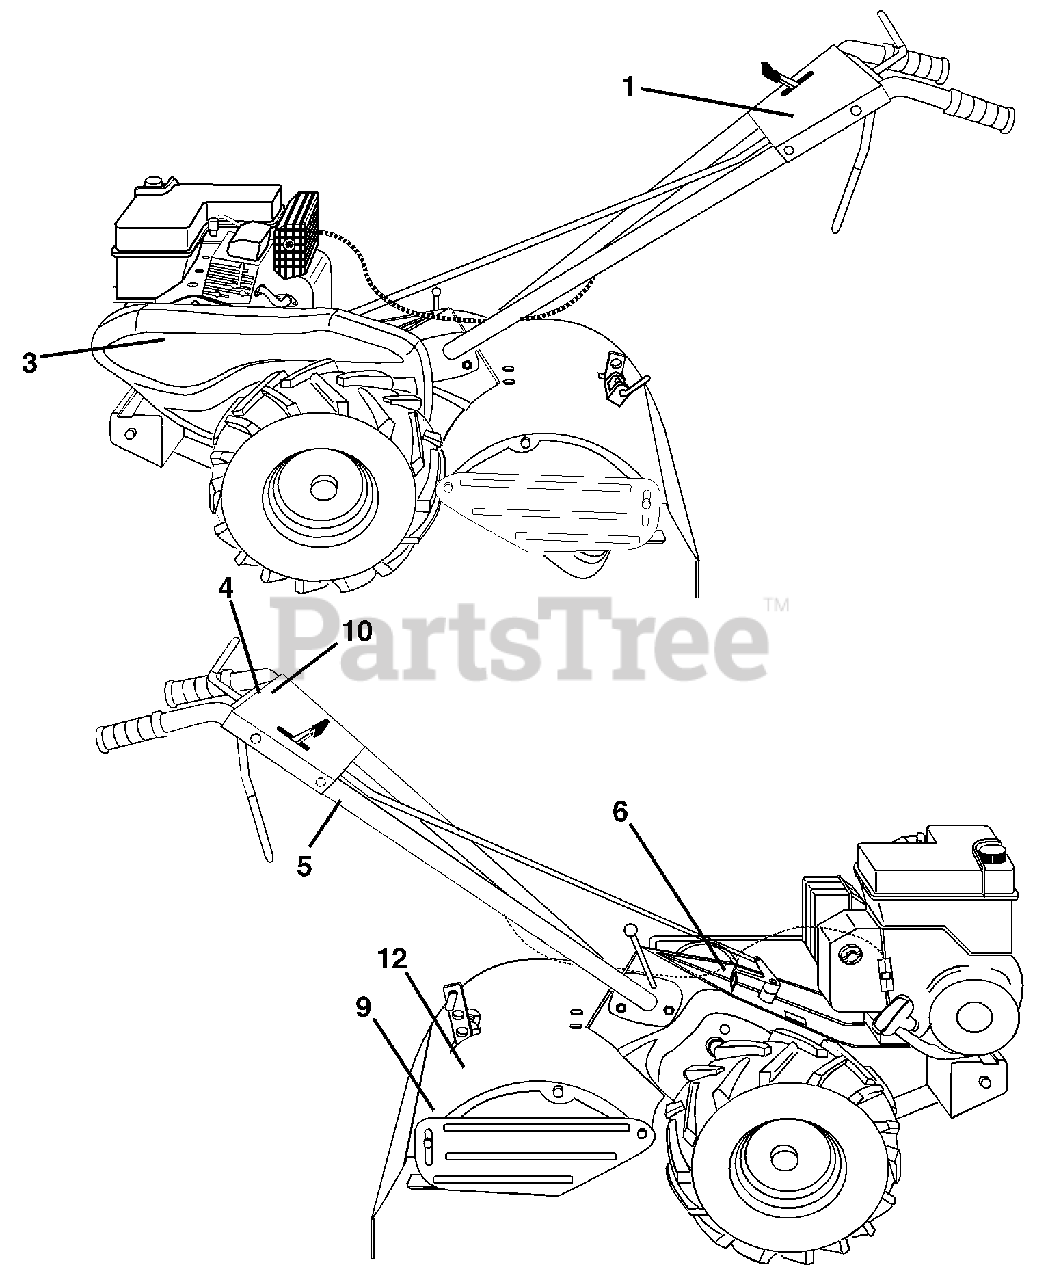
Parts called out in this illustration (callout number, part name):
1	Decal, Logo
3	Decal, Logo
4	Decal, Instruction, Tilling
5	Decal, Hand Placement
6	Decal, Shift Indicator
9	Decal, Warning, Rotating Tines
10	Deal, Reverse
12	Decal, Tine Shield Wrng Dom
